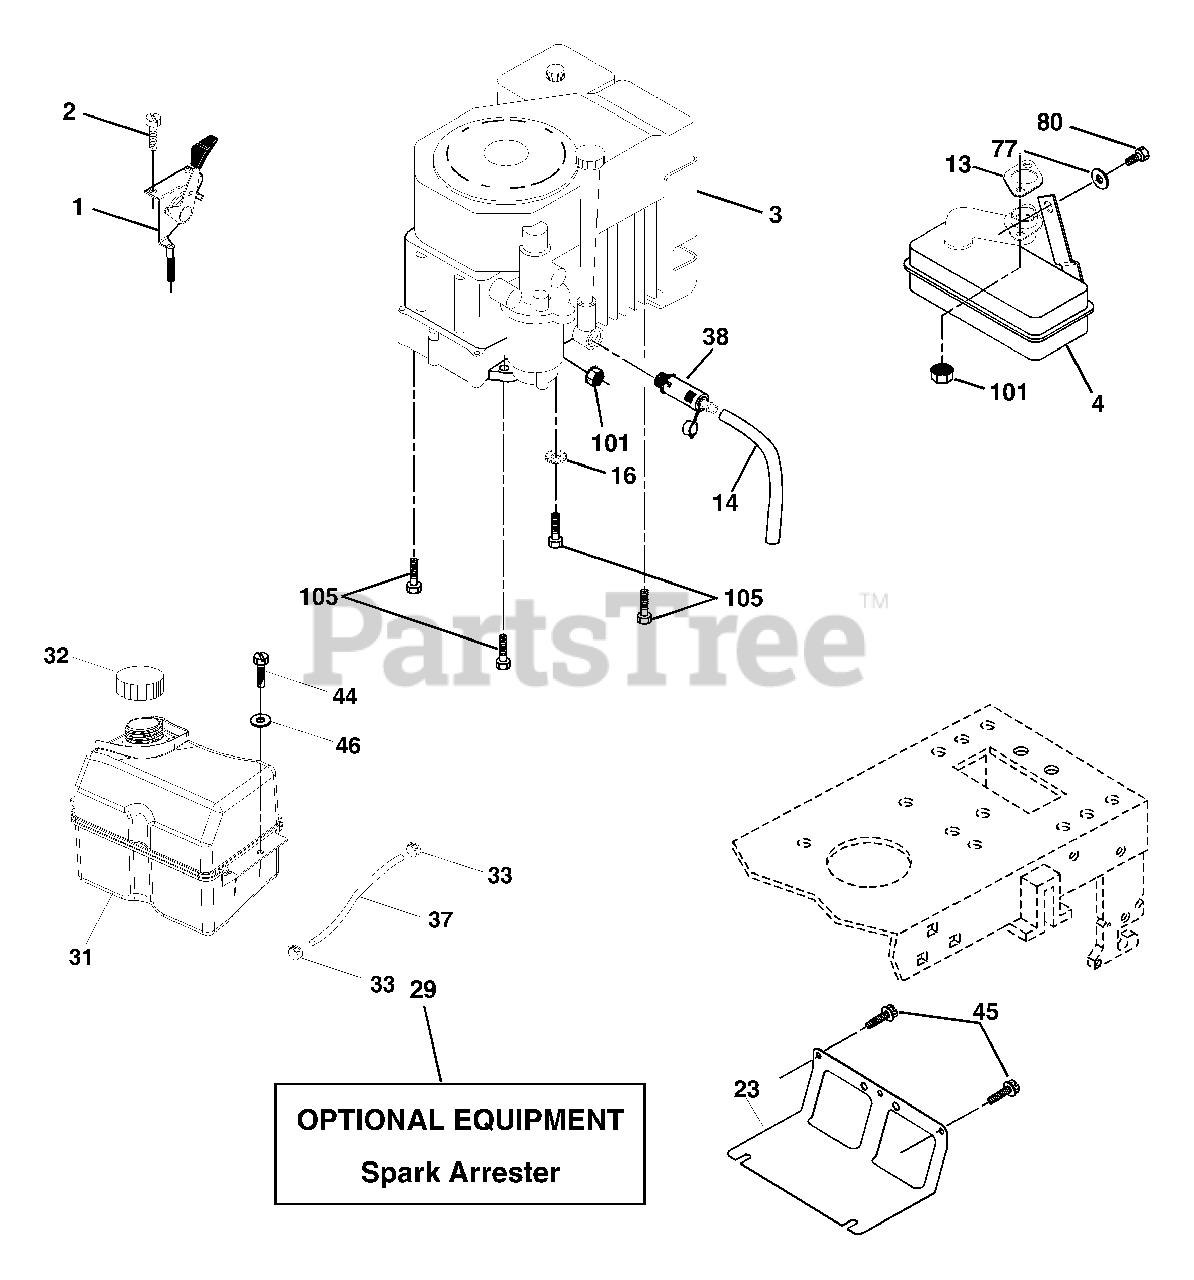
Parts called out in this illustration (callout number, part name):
1	Control Throt /Ch Flag
2	Screw Hex Thd Cut 1/4-20x1/2
4	Muffler Exhaust
14	Tube Drain Oil Easy
16	Washer Lock Ext Tooth 3/8
23	Shield Browning/Debris Guard
29	Arrestor Spark
31	Tank Fuel
32	Cap Asm Fuel W/sym Vented
33	Clamp Hose Blk
37	Line Fuel 20"
38	Plug Drain Oil Easy
44	Screw Hexwsh Thdrol 1/4-20x3/4
45	Screw Hex Wsh Thdrol 3/8-16
46	Washer 9/32 X 7/8 X 16ga
77	Washer 5/16 x 3/4 x 16 Ga.
80	Bolt Hex Hd 5/16-18 Unc x 1/2
101	Nut Flange
105	Screw 3/8-16 x 1
